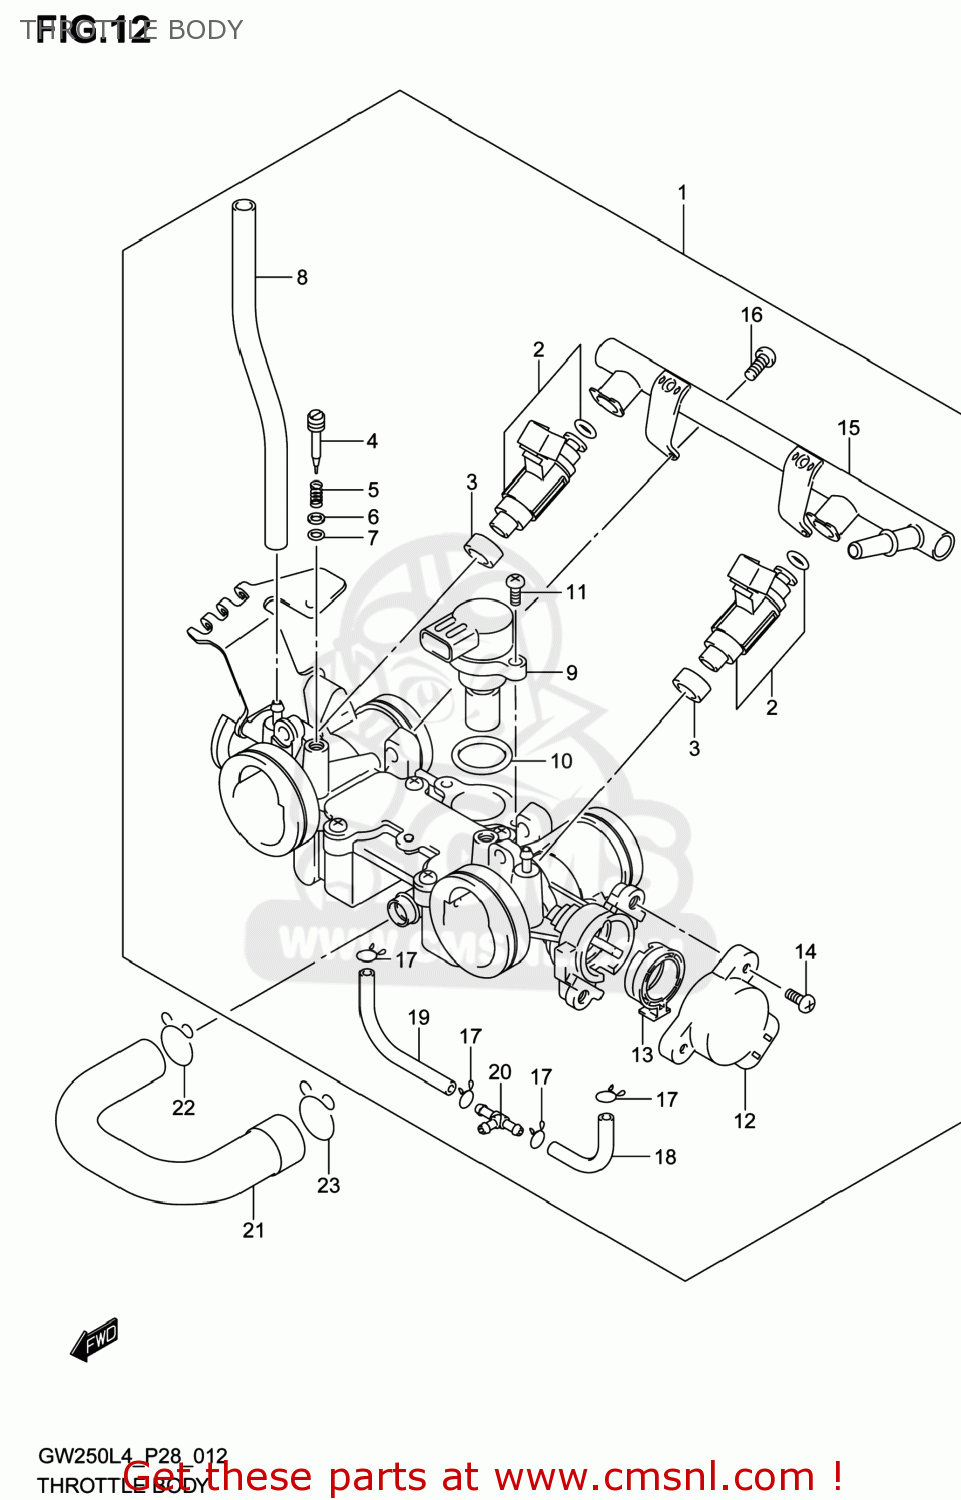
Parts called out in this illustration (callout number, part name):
1	BODY ASSY,THROTTLE
2	INJECTOR ASSY
3	SEAL
4	ADJUSTER
5	SPRING,THROTTLE SCREW
6	WASHER
7	O RING,PILOT AIR SCREW
8	HOSE(3.2X7.4X175)
9	MOTOR ASSY
10	O RING
11	SCREW
12	SENSOR ASSY
13	RING
14	SCREW
15	DELIVERY PIPE
16	SCREW
17	CLIP
18	HOSE
19	HOSE
20	NIPPLE
21	HOSE,ISC VALVE
22	CLIP
23	CLIP
